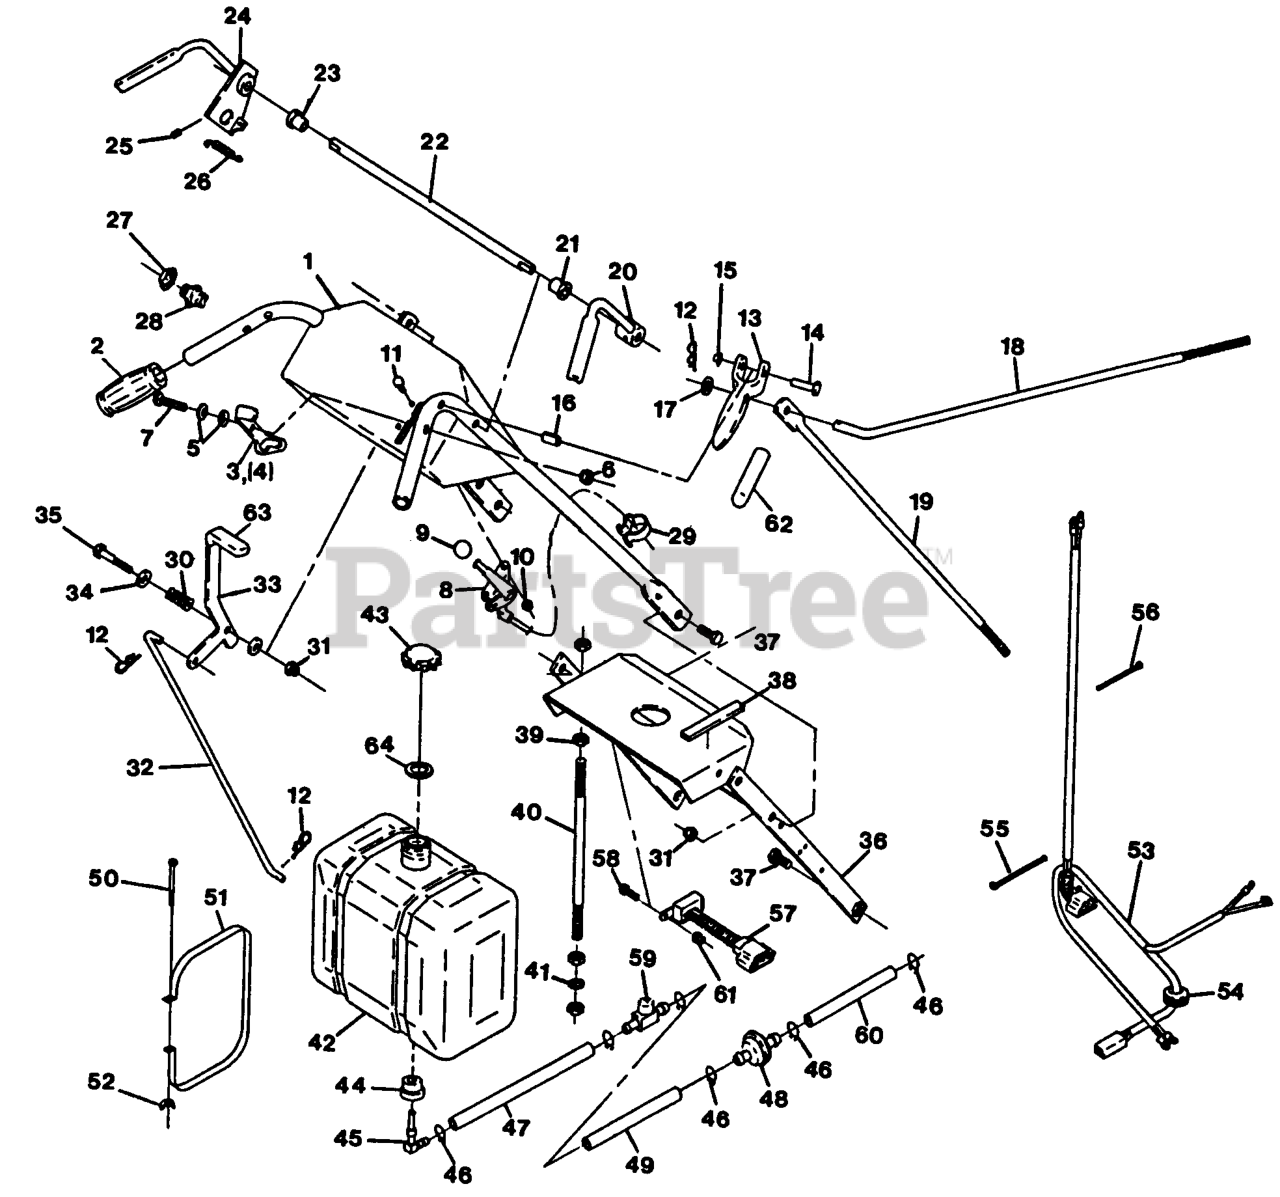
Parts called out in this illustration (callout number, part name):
3	LATCH,W/GRIP RH
4	LATCH,W/GRIP LH
5	WASHER-SPRING
8	CABLE,THROTTLE CONTROL
9	KNOB-BALL
11	BOLT-CARR
12	PIN-COTTER
13	DRIVE LEVER ASM
14	PIN-LEVER, DRIVE
15	NUT-PUSH
16	PIN-ROLL
18	LINKAGE,BRAKE
19	LINKAGE,CALIPER
21	BUSHING-NYLON
22	ROD,CONNECTING
23	BUSHING,FLANGED
25	SCREW-SET
26	SPRING-EXTENSION
28	SWITCH,OPERATOR CNTRL
29	CLIP-CABLE
30	SPRING-COMPRESSION
38	PAD,PLASTIC TANK
43	CAP-FUEL
45	ELBOW-TANK, FUEL
47	FUEL LINE
50	SCRW,MACH CRPH
52	WINGNUT
54	GROMMET
55	TIE-PLASTIC
56	TIE-CABLE
59	VALVE-FUEL
62	GRIP-LEVER, DRIVE
63	GRIP-LEVER
64	GASKET-CAP, TANK
